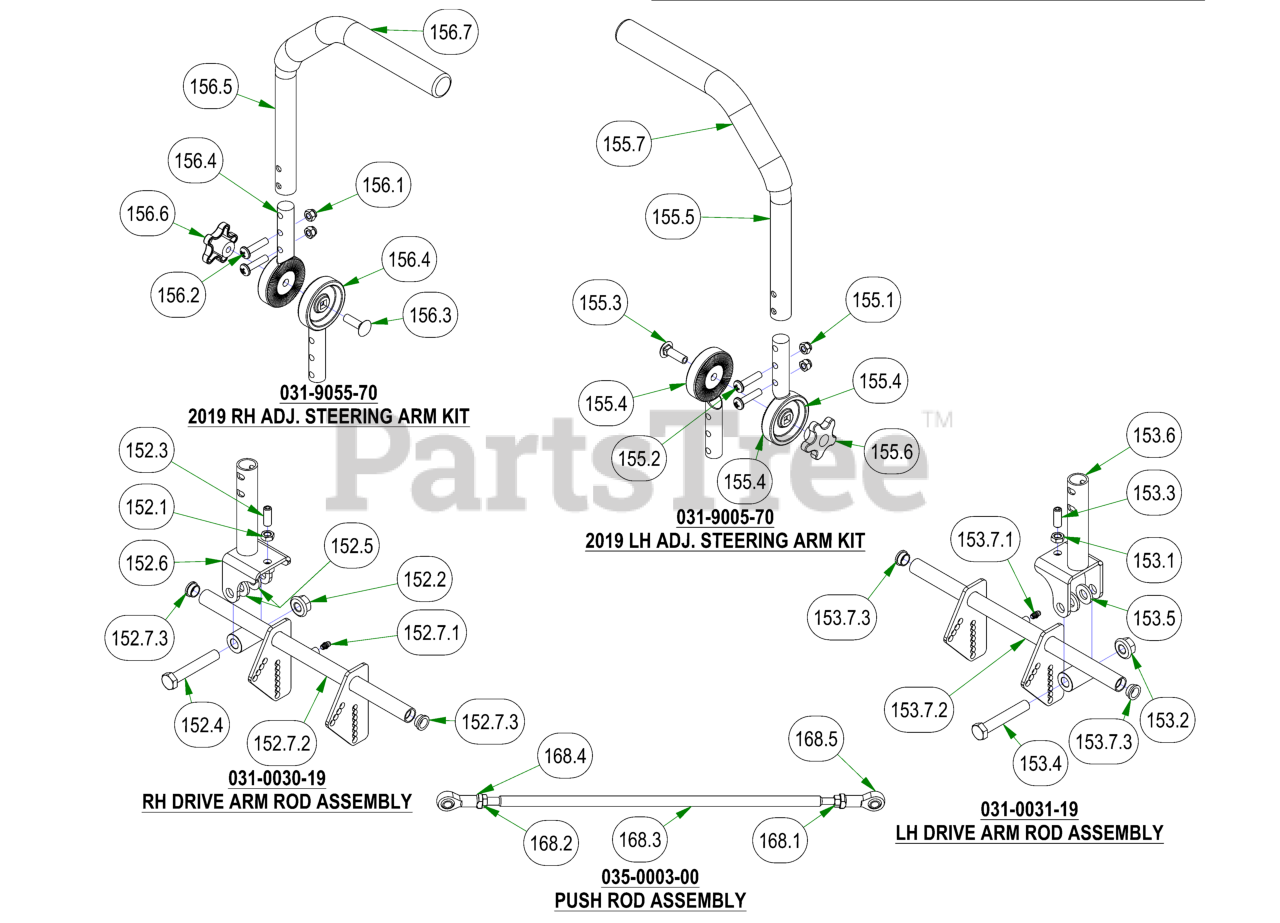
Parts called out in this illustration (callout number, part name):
152	2019 R Series RH Arm Rod Assembly
152.1	3/8-16 Half Jam Nut
152.2	1/2-13 NYLON INSERT FLANGE LOCKNUT ZINC
152.3	3/8-16 X 1 SOCKET SET SCREW (CUP POINT) PLAIN
152.4	1/2-13 X 3 HEX CAP SCREW (GR.5) ZINC
152.5	.505 ID X 1.000 OD X .125 THICK FLAT WASHER NYLON
152.6	Drive Arm Pivot
152.7	2019 Drive Arm Actuator right
152.7.1	1/4" Press in Grease Fitting
152.7.2	2019 Drive Arm Actuator right - Weldment
152.7.3	2019 Drive Arm Bushing
153	2019 R Series LH Arm Rod Assembly
153.1	3/8-16 Half Jam Nut
153.2	1/2-13 NYLON INSERT FLANGE LOCKNUT ZINC
153.3	3/8-16 X 1 SOCKET SET SCREW (CUP POINT) PLAIN
153.4	1/2-13 X 3 HEX CAP SCREW (GR.5) ZINC
153.5	.505 ID X 1.000 OD X .125 THICK FLAT WASHER NYLON
153.6	Drive Arm Pivot
153.7	2019 Drive Arm Actuator left
153.7.1	1/4" Press in Grease Fitting
153.7.2	2019 Drive Arm Actuator left - Weldment
153.7.3	2019 Drive Arm Bushing
155	2019 Left Hand ADJ. Steering Arm Kit
155.1	5/16-18 NYL INS L/N ZC
155.2	5/16-18 x 1 3/8" Futton Head Torx Drive Bolt
155.3	3/8-16 X 1-1/4 CARRIAGE BOLT ZINC
155.4	2019 Steering Arm Adjuster Casting
155.5	2019 Steering Arm Tube
155.6	Black Knob for Adjustable Steering Arm
155.7	Black Steering Arm Grip
156	2019 Right Hand ADJ. Steering Arm Kit
156.1	5/16-18 NYL INS L/N ZC
156.2	5/16-18 x 1 3/8" Futton Head Torx Drive Bolt
156.3	3/8-16 X 1-1/4 CARRIAGE BOLT ZINC
156.4	2019 Steering Arm Adjuster Casting
156.5	2019 Steering Arm Tube
156.6	Black Knob for Adjustable Steering Arm
156.7	Black Steering Arm Grip
168	2019 Rebel Push Rod Assembly
168.1	5/16 LH Nut
168.2	3/8-24 HEX NUT ZINC YELLOW
168.3	2019 Rebel Push Rod
168.4	Spherical Rod End - Outlaw
168.5	Spherical Rod End - Outlaw
